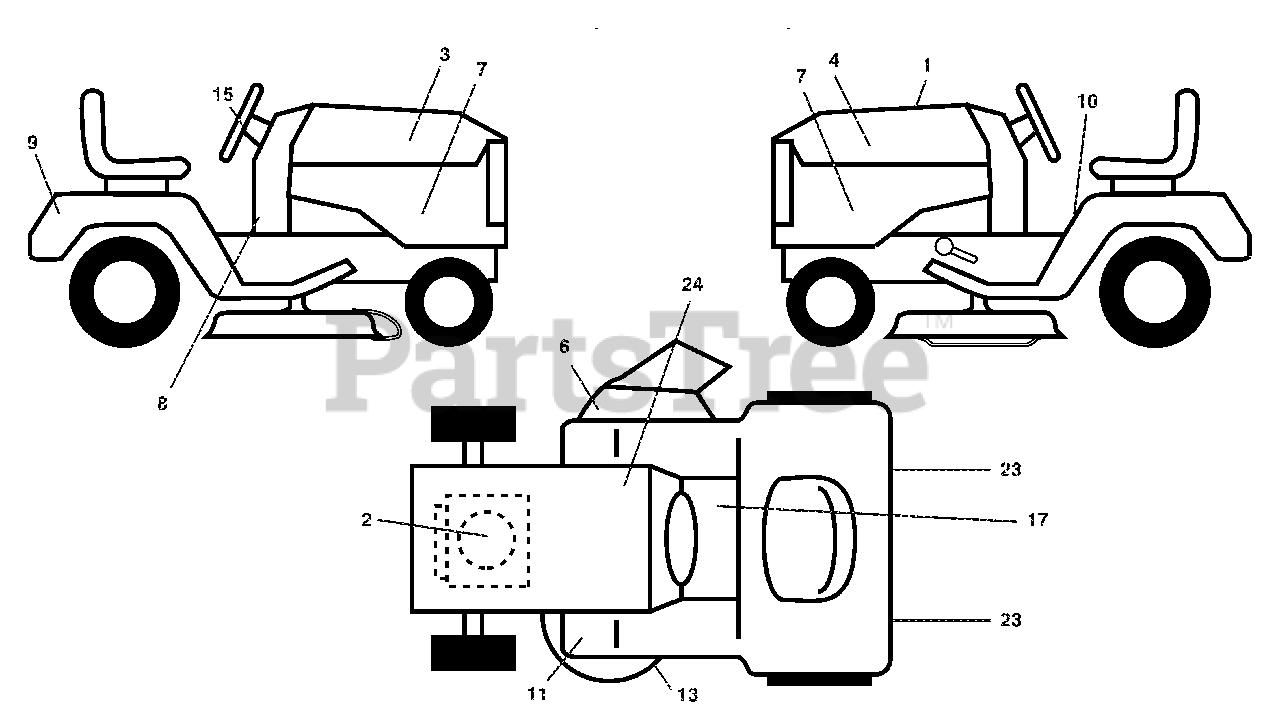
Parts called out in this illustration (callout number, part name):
1	Decal, Replacement Parts
2	Decal, Engine
3	Decal, Hood, RH
4	Decal, Hood, LH
6	Decal, Warning
7	Decal, Side Panel
8	Decal, Dash
9	Decal, Fender
10	Decal, Danger
11	Decal, Foot Rest
13	Decal, V-Belt Sch
15	Decal, Ins. Strg Whl
17	Decal, Saddle Brake Parking
23	Reflector, Taillight
24	Decal, Btry Dngr/Psn
24	Decal, Bypass
24	Decal, Handle Lift (Lift Handle)
